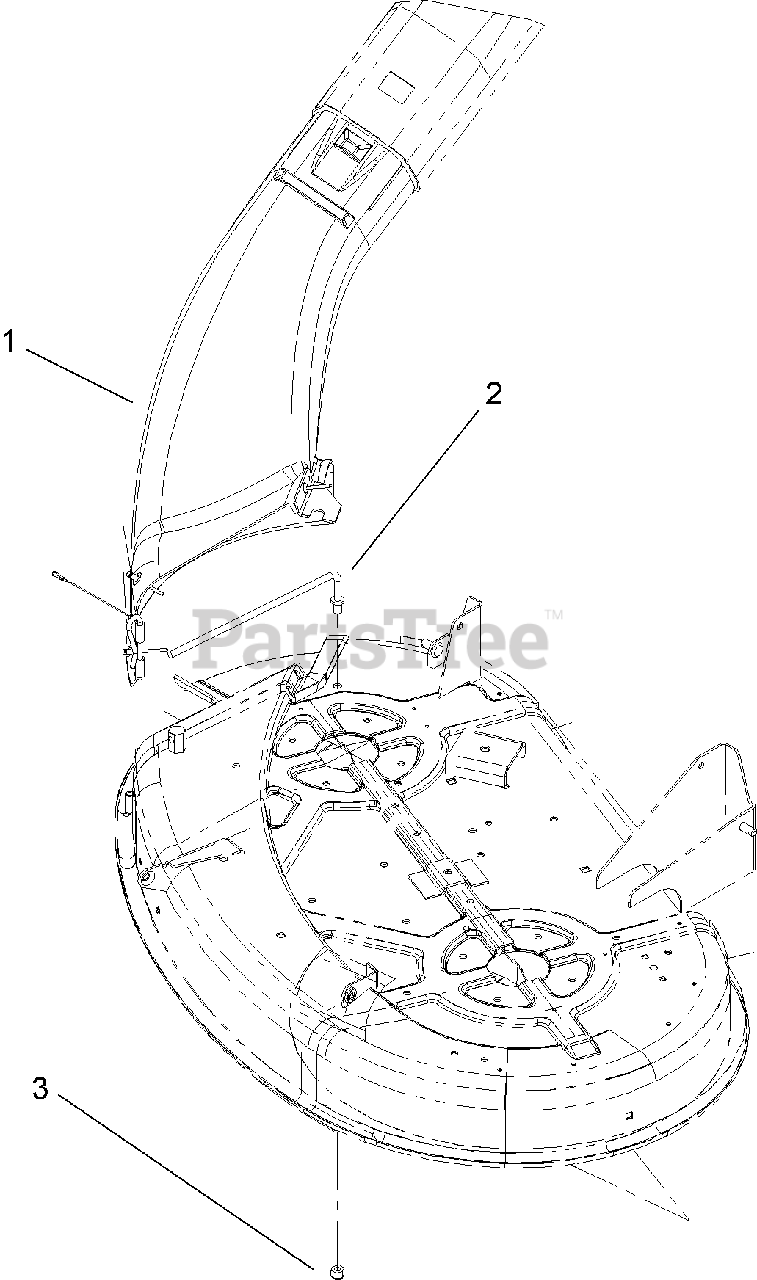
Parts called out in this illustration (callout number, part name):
1	38IN BAGGER CHUTE ASM
2	ROD-PIVOT
3	NUT-LOCK, NI
